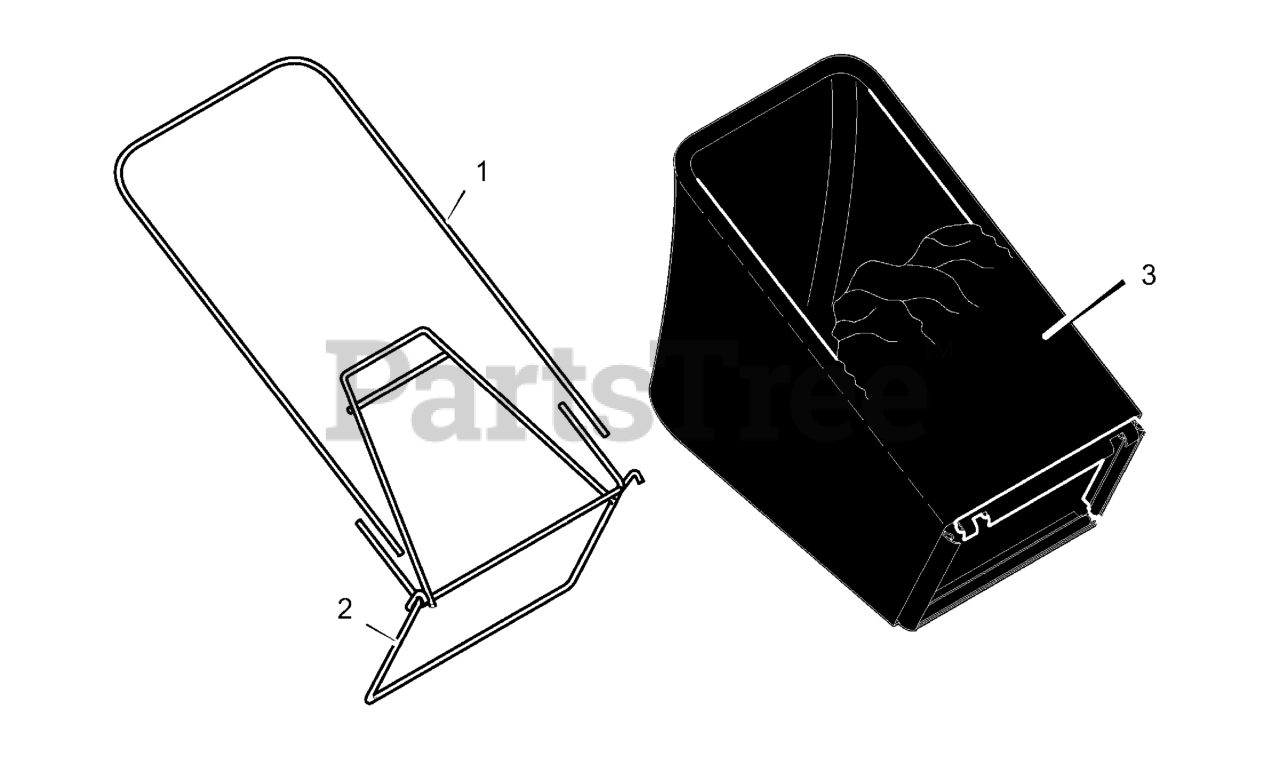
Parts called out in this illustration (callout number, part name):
1	Frame, Top
2	Frame Assembly
3	Bag, Cloth - Black
